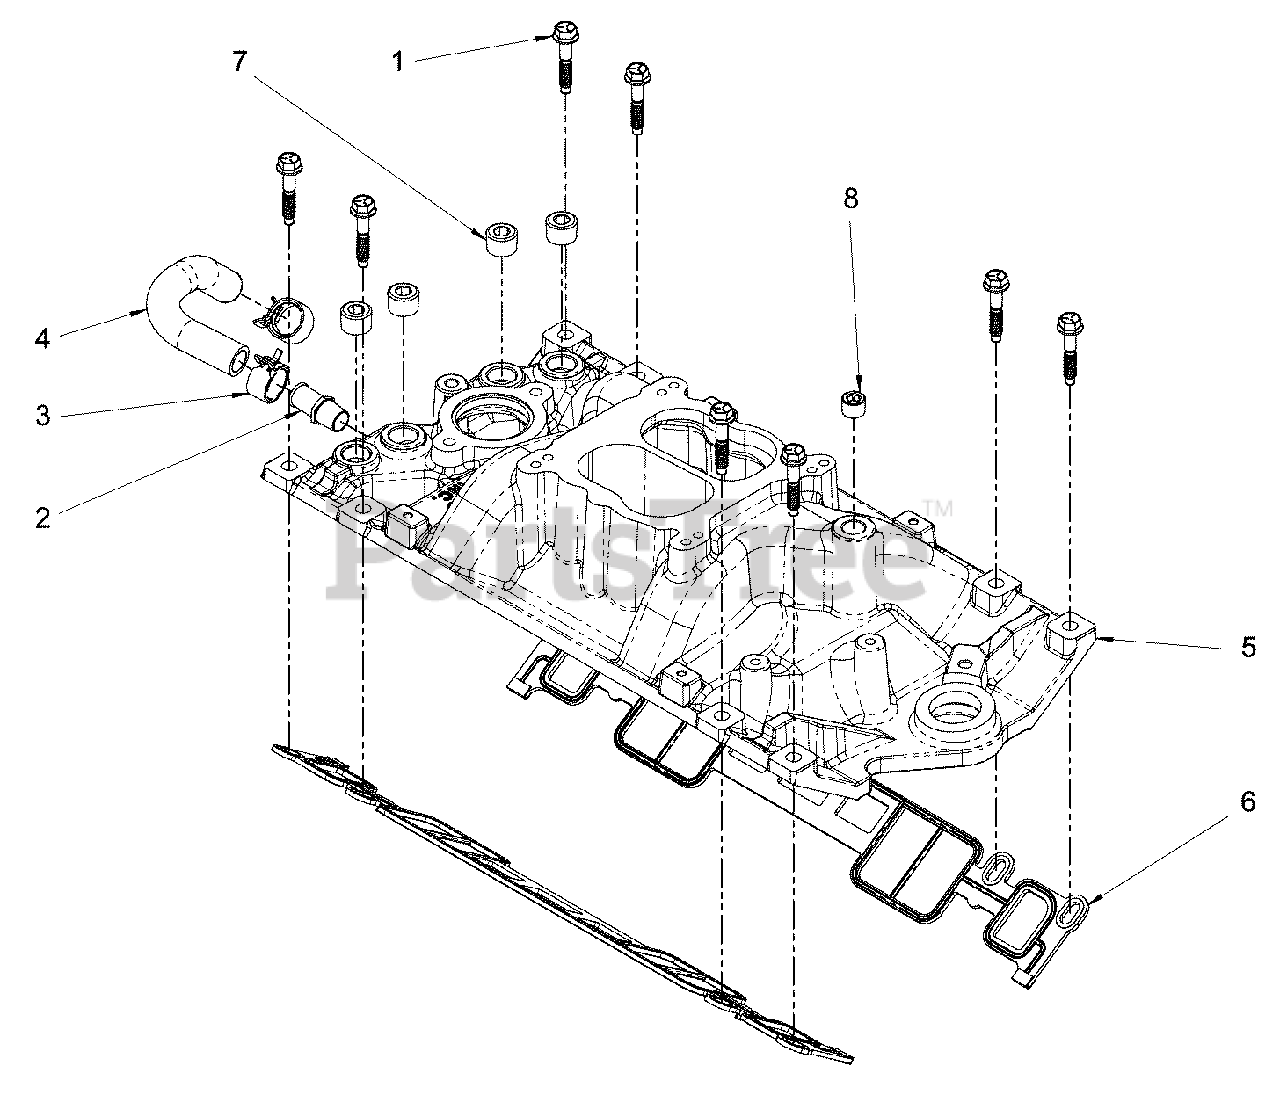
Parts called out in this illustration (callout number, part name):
1	* BOLT
2	* FITTING
3	* CLAMP
5	* INTAKE MANIFOLD
7	* PLUG
8	* PLUG
